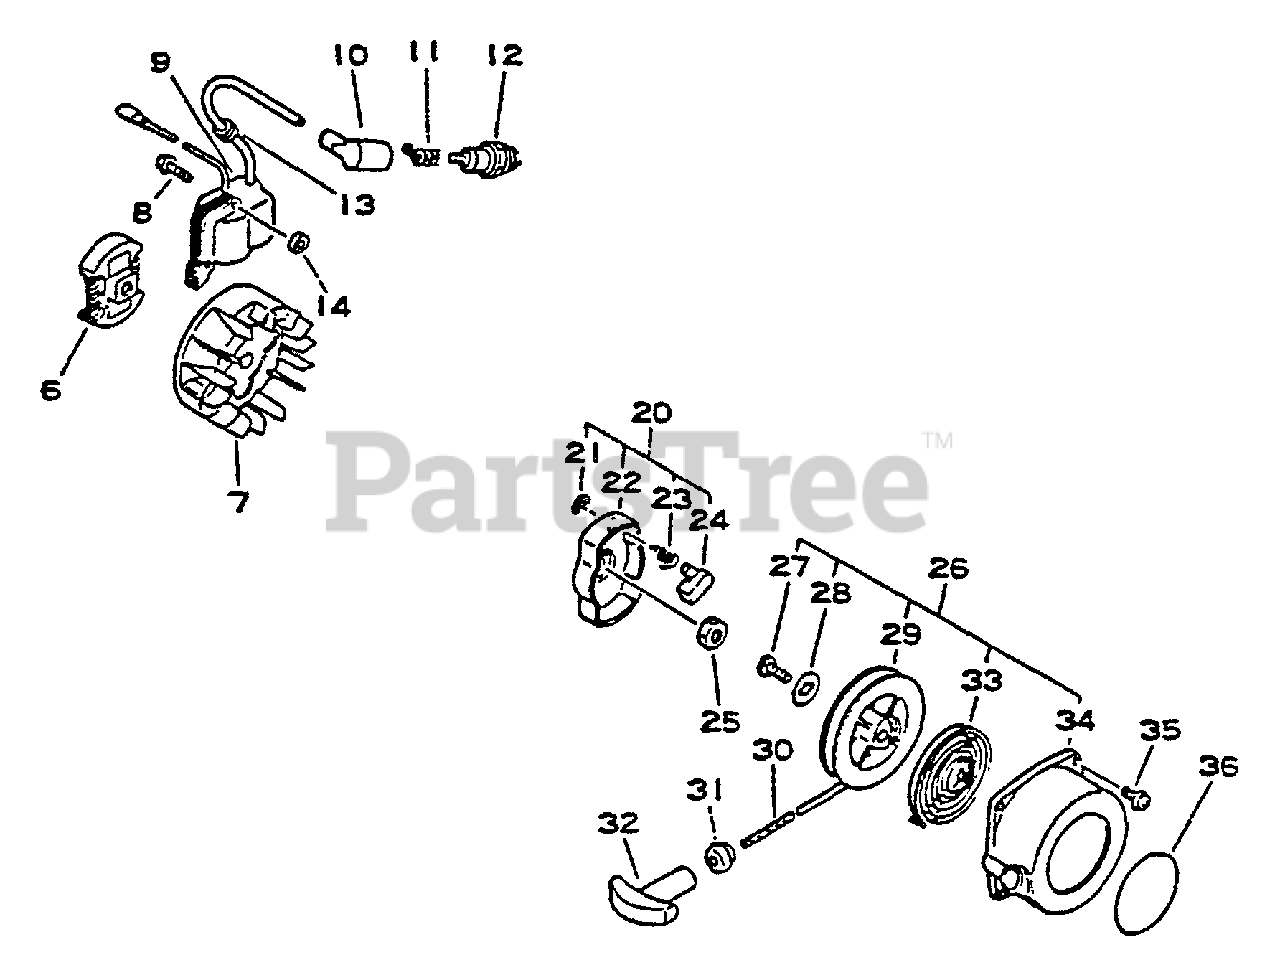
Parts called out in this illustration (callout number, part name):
6	CLUTCH ASSY
7	FLYWHEEL
8	SCREW 4×22
9	COIL, IGNITION
10	CAP, SPARK PLUG
11	TERMINAL, SPARK PLUG
12	SPARK PLUG - BPM7A
12	SPARK PLUG - BPMR7A
20	STARTER PAWL ASSY
21	RING, RETAINING - 6
22	CATCHER, PAWL
23	SPRING, RETURN
24	PAWL, STARTER
25	NUT 8×1.25
26	STARTER ASSY
28	WASHER
29	REEL, ROPE
30	ROPE, STARTER
31	GUIDE, ROPE
32	GRIP, STARTER
33	SPRING, RECOIL
34	CASE, RECOIL STARTER
35	SCREW 4×16
36	LABEL - ECHO
